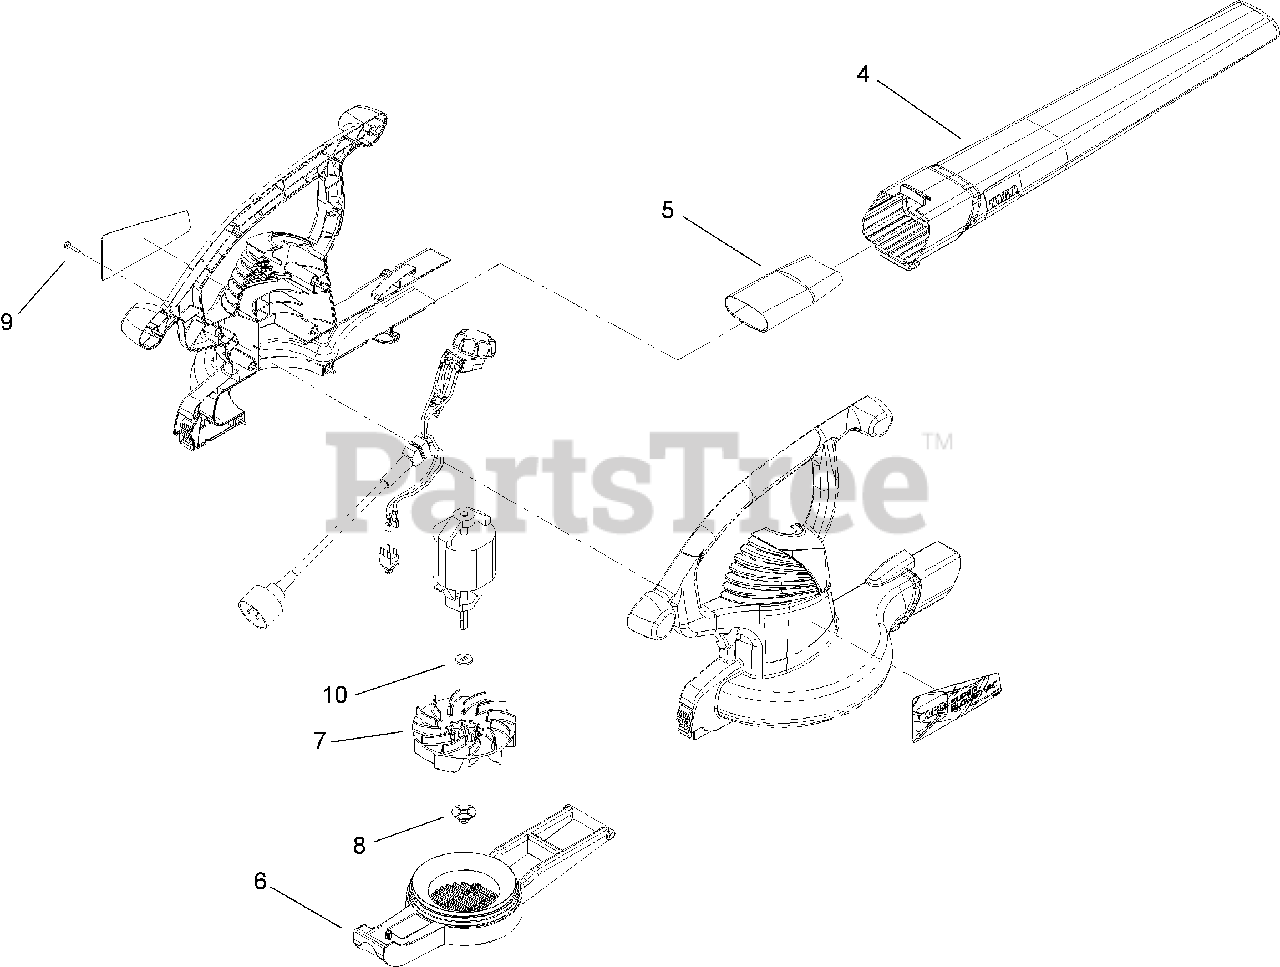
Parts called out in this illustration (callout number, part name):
4	TUBE-BLOWER
5	EXTENSION-TUBE, ULTRA
6	COVER-INLET
7	IMPELLER-MAGNESIUM
8	NUT-HEX
9	SCREW-PPH
10	WASHER-IMPELLER
